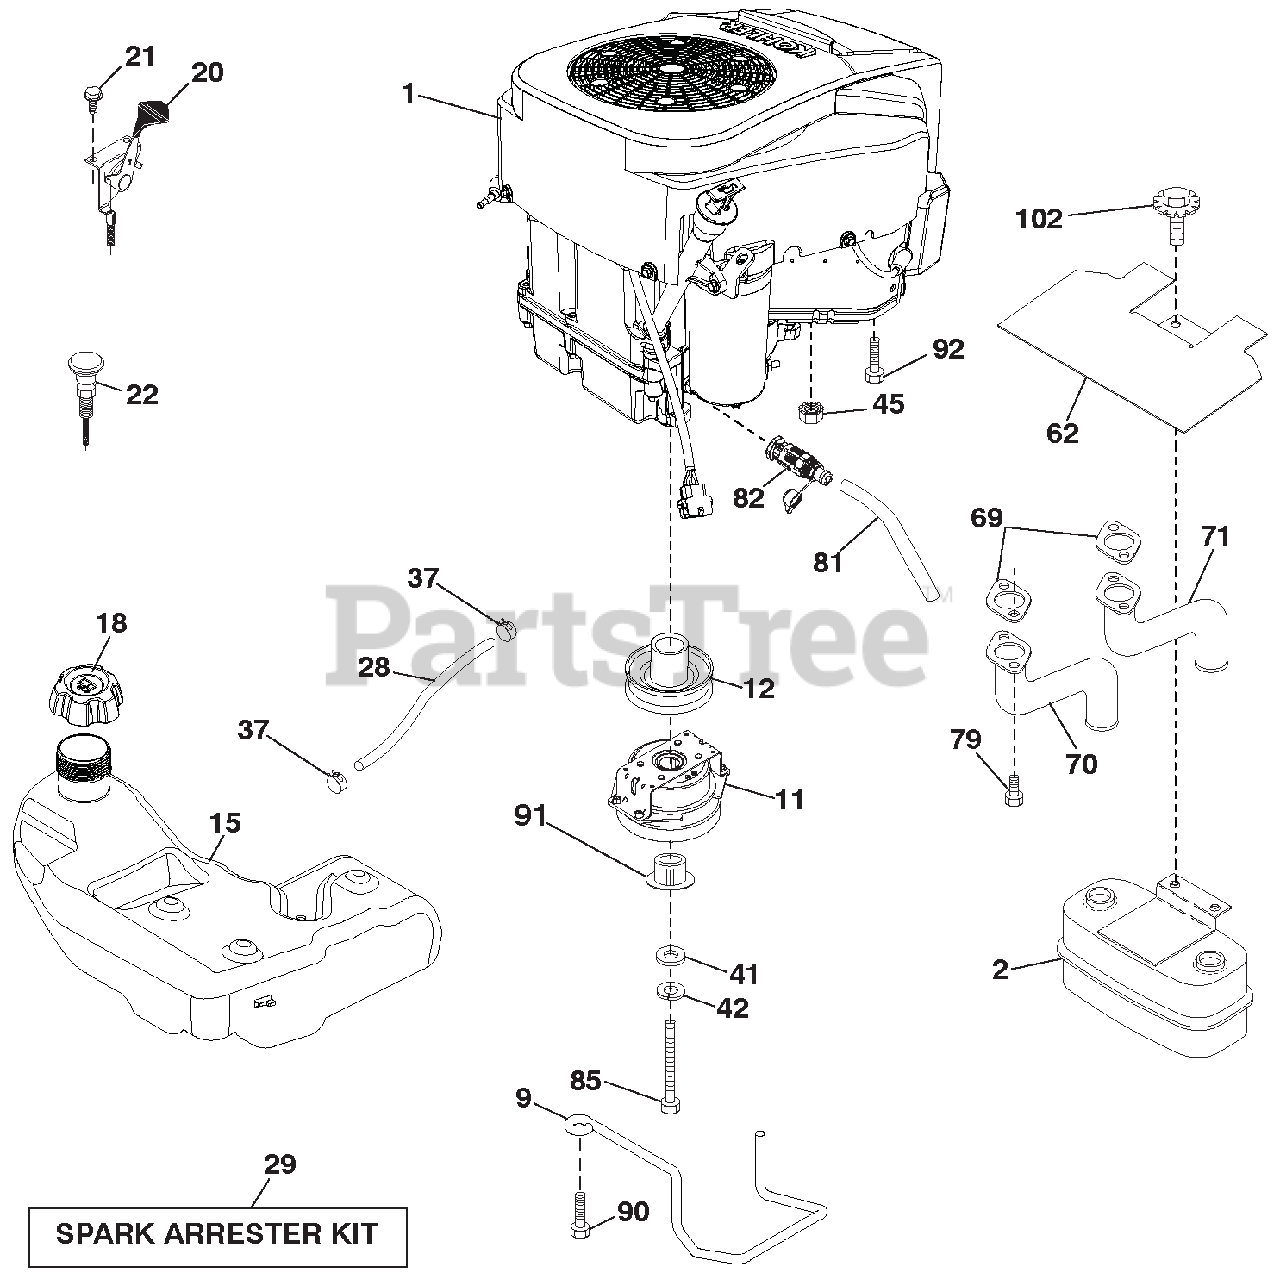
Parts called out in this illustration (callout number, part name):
1	ENGINE KOHLER MODEL NO. KT740-3014(585445901)(ORDER PARTS FROM ENGINE MANUFACTURER.)
2	MUFFLER ASM.TWIN.LO-TONE
9	KEEPER.BELT.ENGINE
11	ELECTRIC CLUTCH
12	PULLEY.ENGINE.TUFFTORQE.1"CRK.
15	TANK.FUEL.SIDE-FILL.3.00 GA.
18	CAP FUEL
20	CONTROL.THROTTLE
22	CONTROL CHOKE
28	LINE.FUEL.20"
29	KIT.SPARK ARRESTOR(392390 B&S)
37	CLAMP.HOSE.BLK.
41	WASHER.1-1/2 ODX15/32 IDX.250
42	WASHER.LOCK.HVY HLCL.SPR.7/16
45	Nut, Keps Hex 1/4-20 unc
62	SHIELD.HEAT.MUFFLER.
70	EXHAUST TUBE LH
71	EXHAUST TUBE RH
79	SCREW.SOCKET HD.5/16-18 X .75
81	TUBE.DRAIN.OIL.EASY
82	VALVE OIL DRAIN
85	BOLT.HEX.7/16-20 X 3.75 X GR.
90	SCREW.3/8-16X1.SMGML.TAP/R.BLK
91	BUSHING.1.375OD.HEYCO 2210
92	SCREW.3/8-16 X 1.SMGML.TAP/R
102	SCREW.5/16-18X3/4.SMGML.TAP/BL
